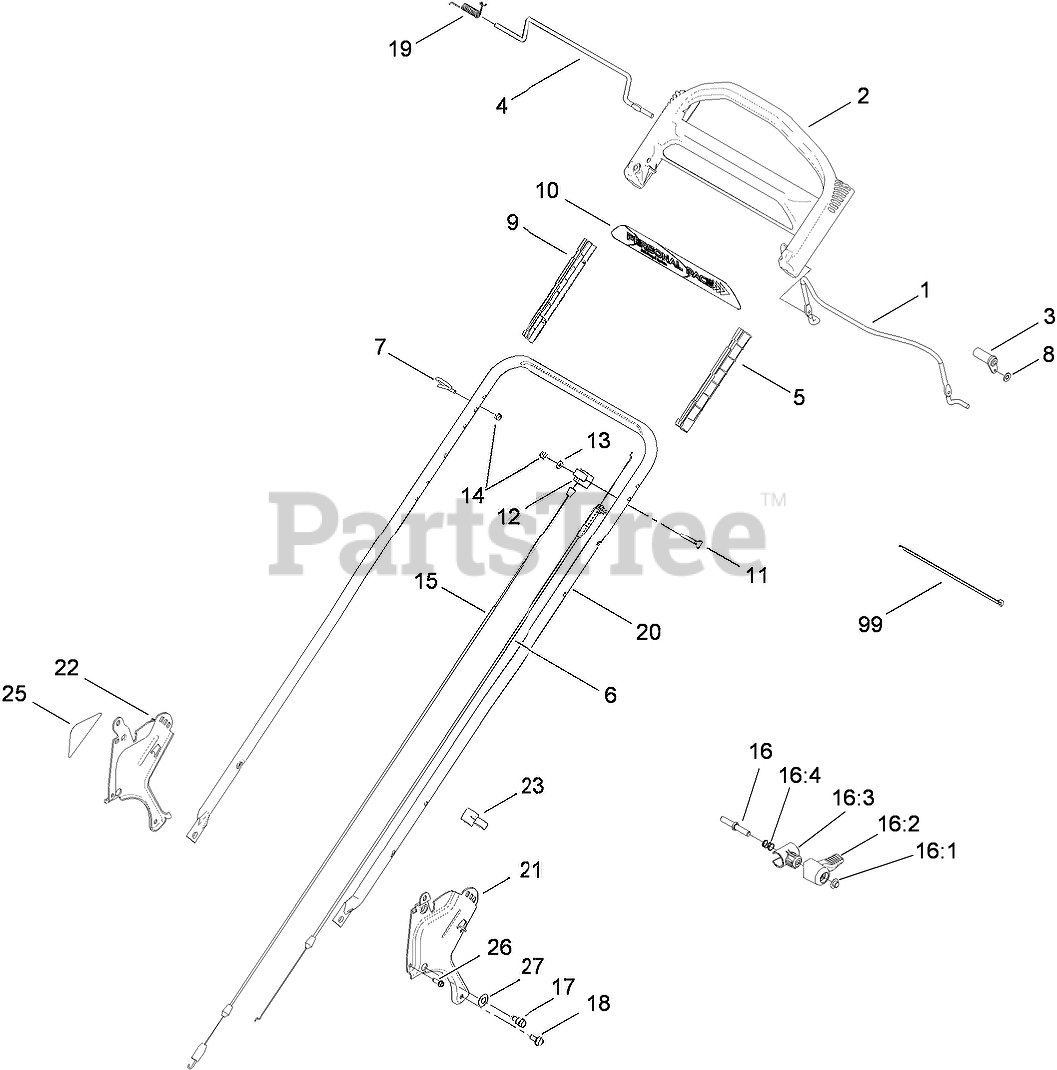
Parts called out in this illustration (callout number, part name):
1	Bail-Brake
2	HANDLE-CONTROL
3	LEVER-TRACTION
4	BAR-CONTROL, TRACTION
5	GUIDE-LH
6	CABLE-BRAKE
7	GUIDE-ROPE
8	WASHER-PLAIN
9	GUIDE-RH
10	DECAL-HANDLE
11	SCREW
12	ANCHOR-CABLE
13	WASHER-FLAT
14	NUT-LOCK, NI
15	CABLE-TRACTION
16	QUICK RELEASE ASM
16:1	NUT-PUSH
16:2	LEVER
16:3	ANCHOR-SPRING
16:4	SPRING-COMPRESSION
17	BOLT-SHOULDER
18	SCREW-HWHTF
19	Spring-Torsion
20	HANDLE
21	BRACKET-HANDLE, LH
22	BRACKET-HANDLE, RH
23	Guide-Cable
25	DECAL-INSTRUCTION
26	SCREW-HWHTF
27	WASHER-SPRING, CONICAL
99	TIE-CABLE
